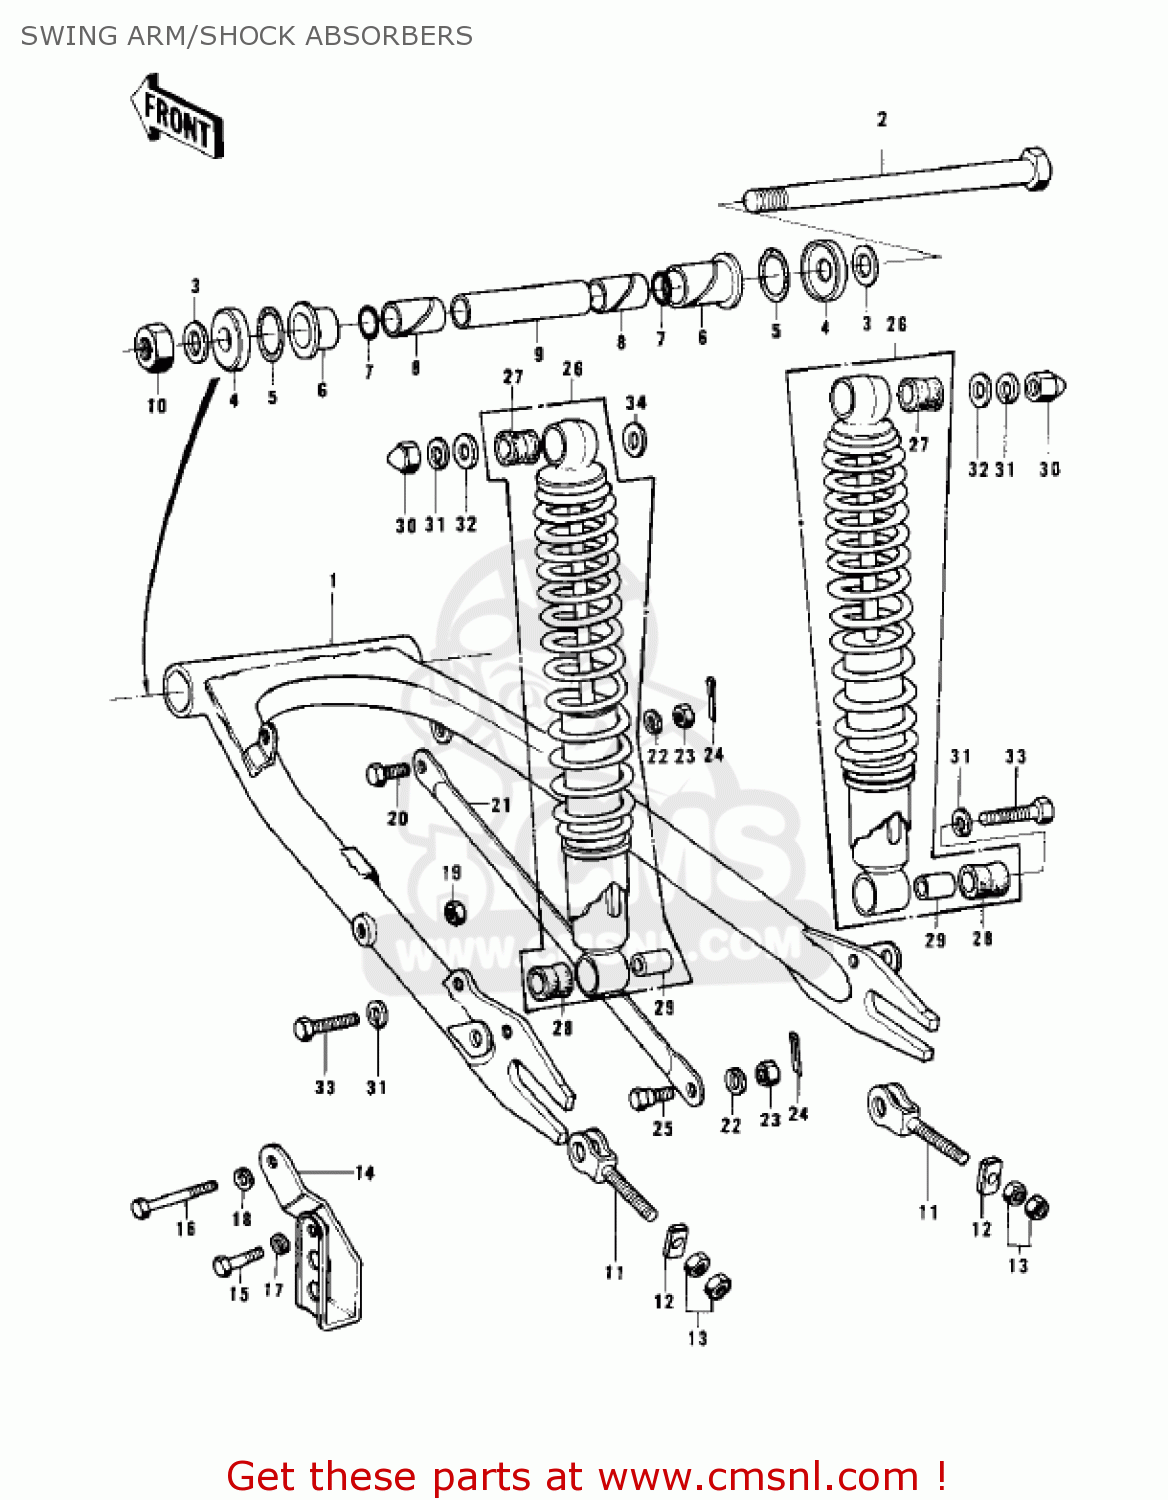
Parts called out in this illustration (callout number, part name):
1	SWING ARM
2	SHAFT-SWING ARM
3	WASHER-PLAIN-SMALL,12
4	CAP,SWING ARM
5	O RING,30MM
6	BUSHING,SWING ARM
7	O RING,16MM
8	SLEEVE,12.1X22X39
9	COLLAR,12.7X17.3X106
10	NUT,LOCK,12MM
11	ADJUSTER,CHAIN
12	PLATE,CHAIN ADJUSTER
13	NUT,8MM
14	GUARD,CHAIN
15	BOLT-HEX,HEAD 8X16
16	BOLT,HEX HEAD,10X50
17	WASHER-SPRING,8MM
18	WASHER-SPRING,10MM
19	NUT,10MM
20	BOLT,HEX HEAD,8X24
21	TORQUE LINK,RR BRAKE
22	WASHER-SPRING,8MM
23	NUT,8MM
24	PIN-COTTER,2.0X20
25	BOLT,RR TORQUE LINK
26	SHOCKABSORBER,REAR
27	BUSH A-SHCK ABS RUBER
28	DAMPER,SHOCKABSORBER
29	COLLAR,SHOCKABSORBER
30	NUT-SHOCK ABSORBER
31	WASHER-SPRING,10MM
32	WASHER,10.5X26X2.3
33	BOLT-HEX HEAD,10X35
34	WASHER-PLAIN-SMALL,12
